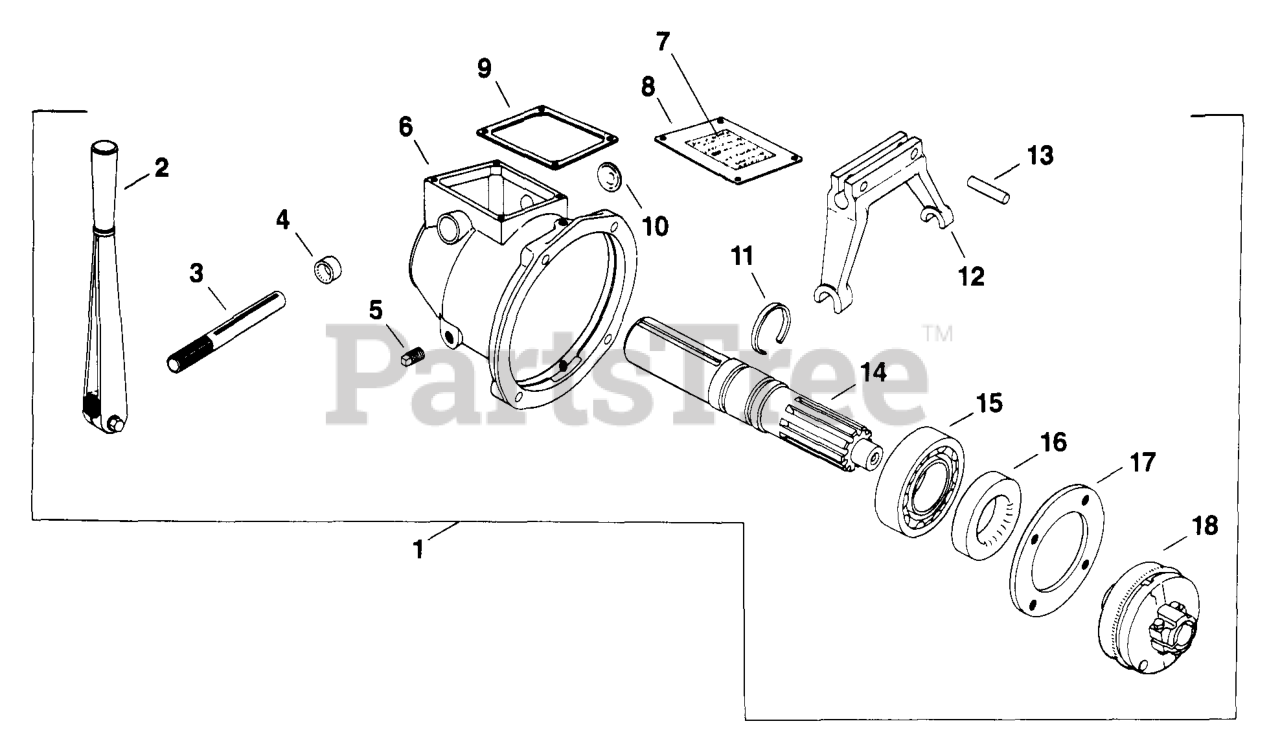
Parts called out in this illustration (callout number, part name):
1	CLUTCH - USE 48 239 02
1	CLUTCH - DISCONTINUED
2	LEVER - DISCONTINUED
3	SHAFT - DISCONTINUED
5	PLUG,PIPE 1/4 NPTF SQUARE HD USE 25 139 53-S
8	COVER - DISCONTINUED
9	GASKET - DISCONTINUED
10	PLUG - USE X-230-20
11	RING - DISCONTINUED
12	YOKE - USE 24 471 01
14	SHAFT - DISCONTINUED
15	BEARING - DISCONTINUED
17	PLATE - DISCONTINUED
18	Clutch - assembly (See pg. 29)
4814102-S	RING, SNAP - DISCONTINUED
